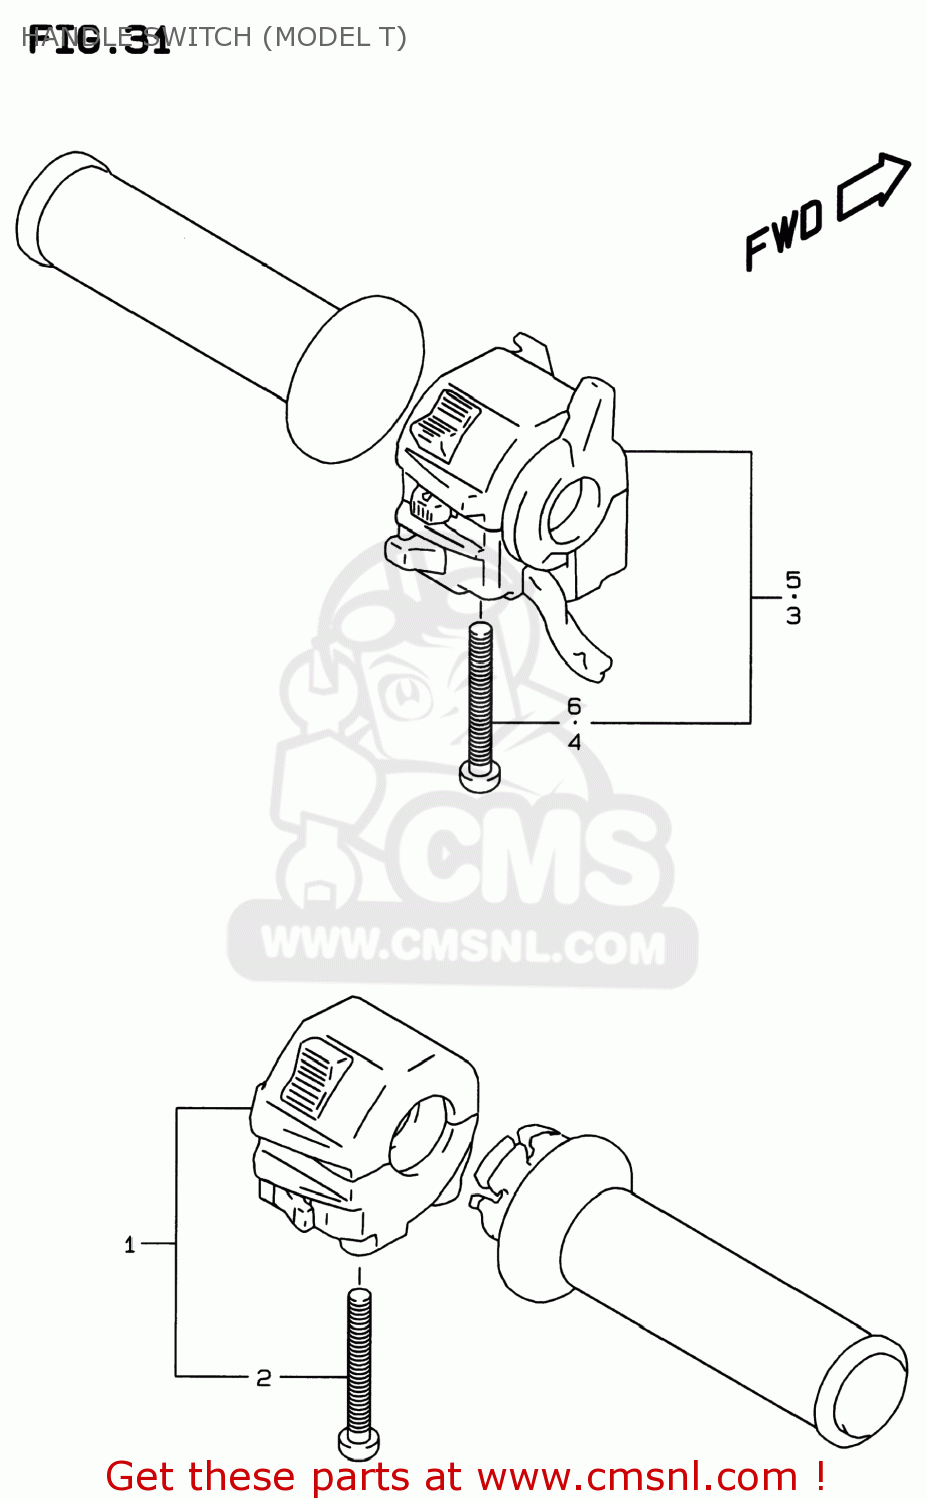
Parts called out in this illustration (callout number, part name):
1	SWITCH ASSEMBLY,HANDLE,RIGHT
2	SCREW, 5X45
3	SWITCH ASSY,HANDLE,L
4	SCREW
5	SWITCH ASSEMBLY,HANDLE,LEFT
6	SCREW, 5X45
